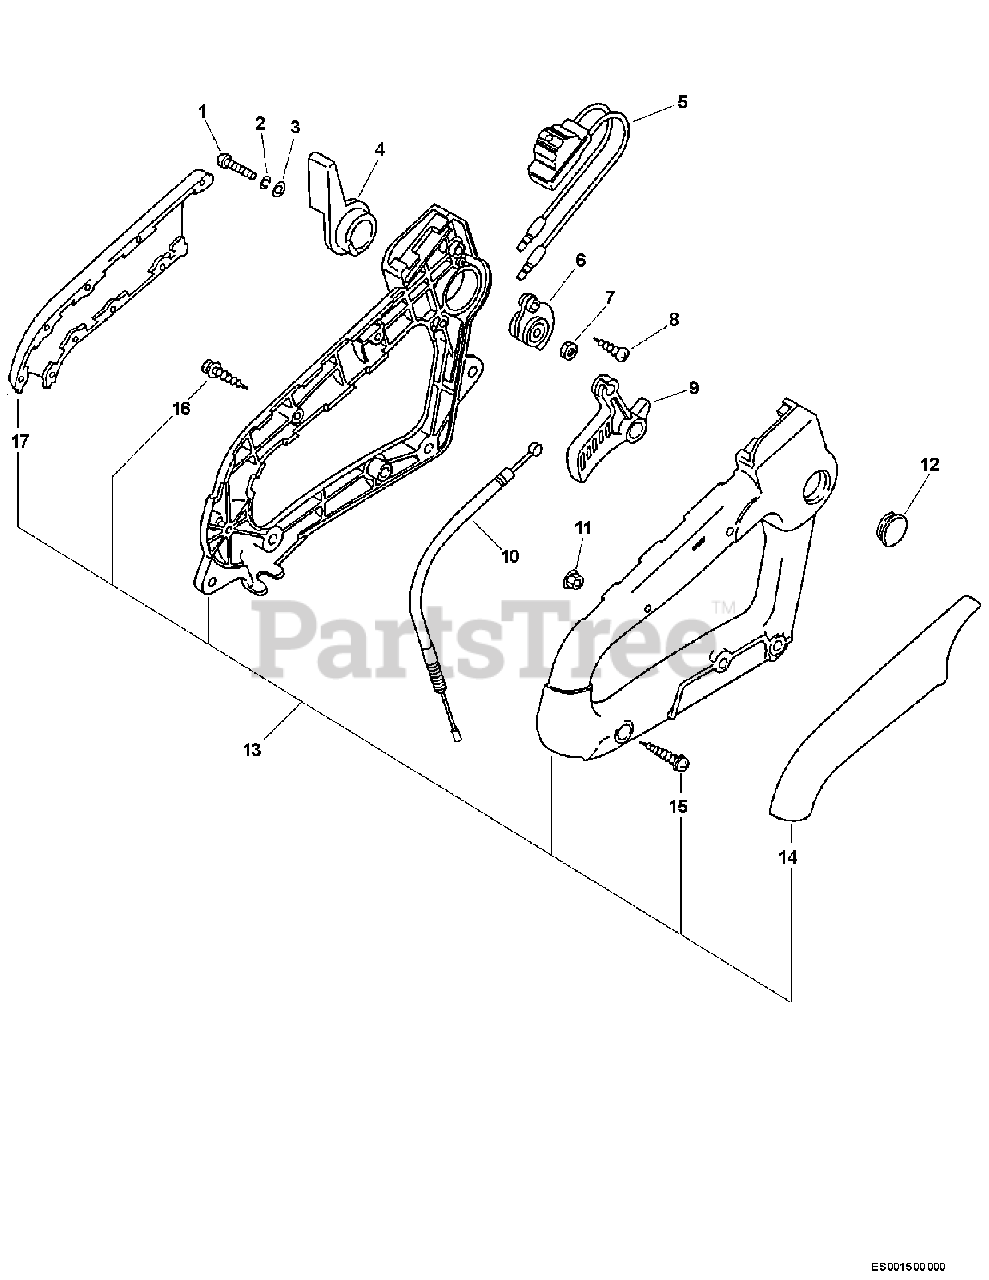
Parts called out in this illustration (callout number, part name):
1	SCREW - 6X20
2	LOCKWASHER - 6
3	WASHER - 6
4	CONTROL, THROTTLE
5	IGNITION SWITCH ASSY
6	BRACKET, THROTTLE
7	LOCKNUT - 6
8	SCREW - 4X10
9	TRIGGER, THROTTLE
10	CABLE, THROTTLE
11	NUT - 5 -- FLANGE
13	HANDLE SET - REAR
14	GRIP, HANDLE - RIGHT
15	SCREW - 5X30
16	SCREW - 4X22
17	GRIP, HANDLE - LEFT
